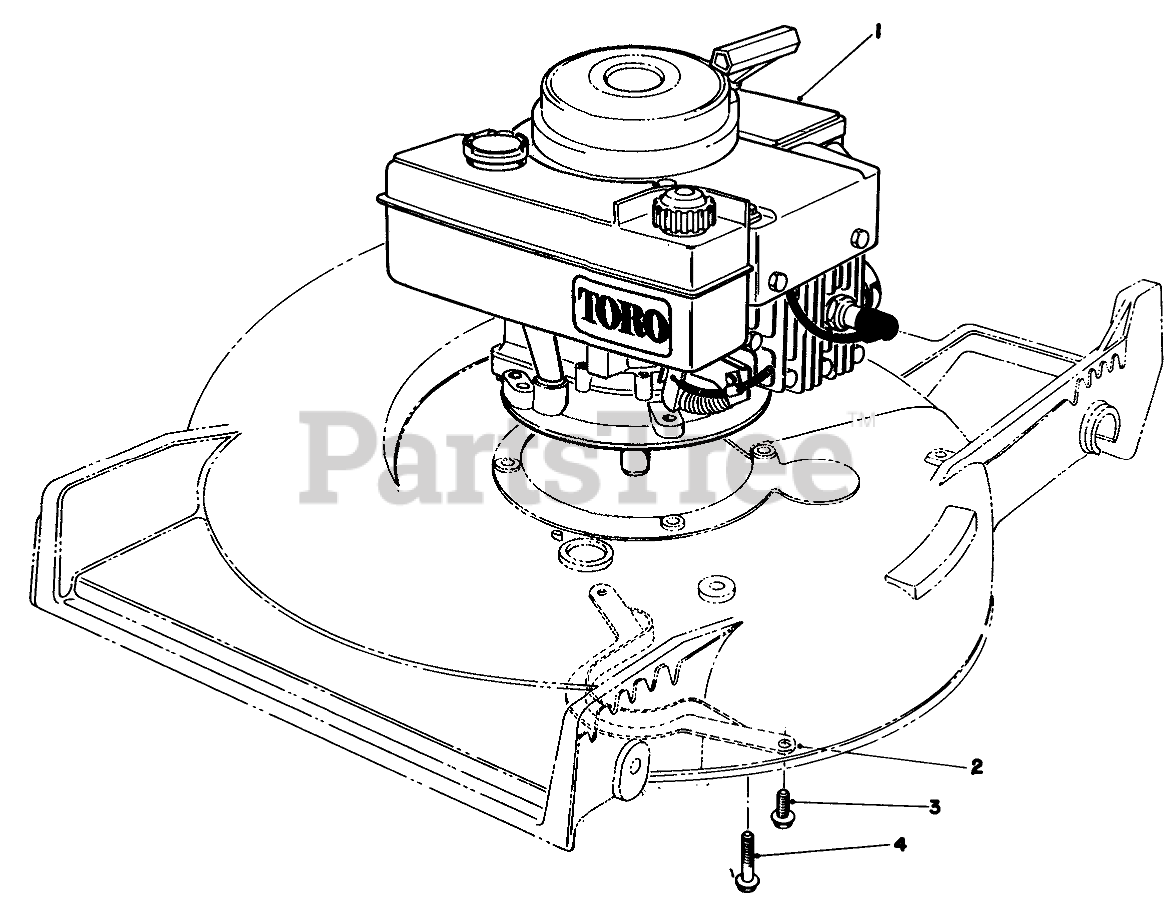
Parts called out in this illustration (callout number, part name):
2	BBC BELT GUIDE
3	Screw
4	3/8-16 X 2 CAPSCREW
